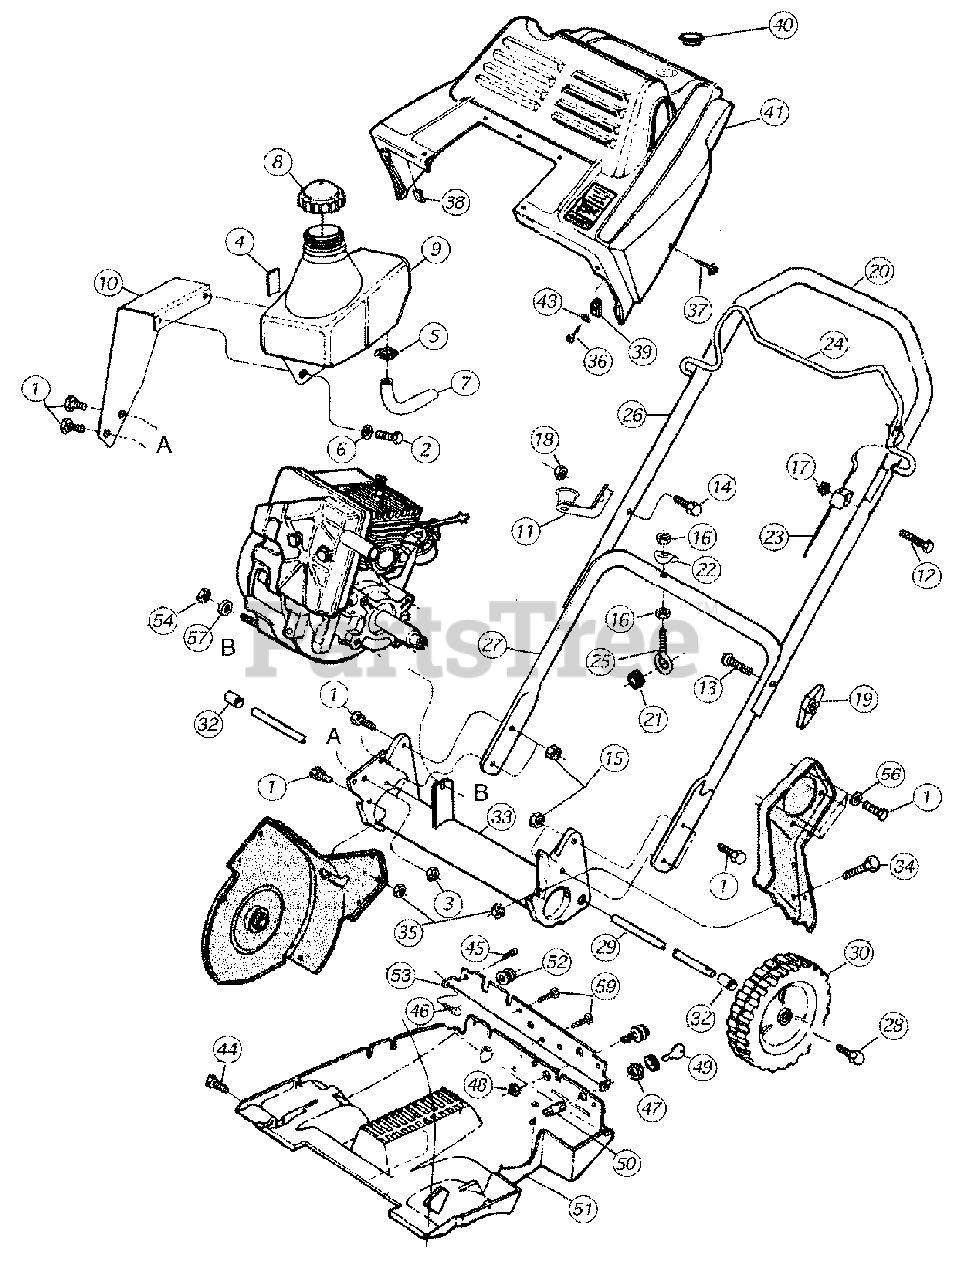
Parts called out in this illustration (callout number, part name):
1	Hex Screw: 5/16 - 18 x .75 Gr 2
2	Hex Screw: 1/4 - 14 x .625
3	Nylock Nut 32 750-1069 Spacer
4	Foam Strip
5	Hose Clamp 1/2" OD
6	Flat Washer
7	Hose, Fuel Line
8	Fuel Tank Cap
9	Fuel Tank
10	Support Bracket
11	Bracket Assembly, Rope Guide
12	Hex Screw: 1/4 - 20 x 2.0 Gr 5
13	Carriage Bolt: 5/16 - 18 x 2.0 Lg. Carved
14	Oval C-Sunk Screw
15	Nylock Nut
16	Hex Nut: 5/16 - 18
17	Top Lock Nut Nylon Insert
18	Top Lock Nut 1/4 - 20
19	Knob Assembly
20	Foam Grip, Handle
21	Grommet: .44 ID x .94 OD x .50
22	Side Lock Washer
23	Drive Cable, Auger
24	Auger Bail, Drive Dipped
25	Eye Bolt 5/16 - 18
28	Tap Screw: 3/8 - 16 x .5
29	Axle, Tube
30	Wheel Assembly
32	Spacer
33	Frame Assembly
34	Hex Cap Screw: 5/16 - 18 x 1.00
35	Nylock Nut
36	Hex Screw
37	Ab Screw
38	Retainer Clip, U-Style
39	U Nut
40	Snap-In Plug
41	Upper Engine Cover
43	Flat Washer
44	Hex Screw: 1/4 - 20 x .625
45	Tap Screw: 10 - 24 x .75
46	Tap Screw: 10 - 25 x .75
47	Jam Nut: 5/8 - 32 x .12
48	Top Lock Nut Nylon Insert
49	Ignition Key
50	Recoil Starter Key
51	Lower Engine Cover
52	Grommet: .280 x .750 x .40
53	Control Panel
54	Nylock Nut
56	Lock Washer
57	Flat Washer
59	Cord Assembly
